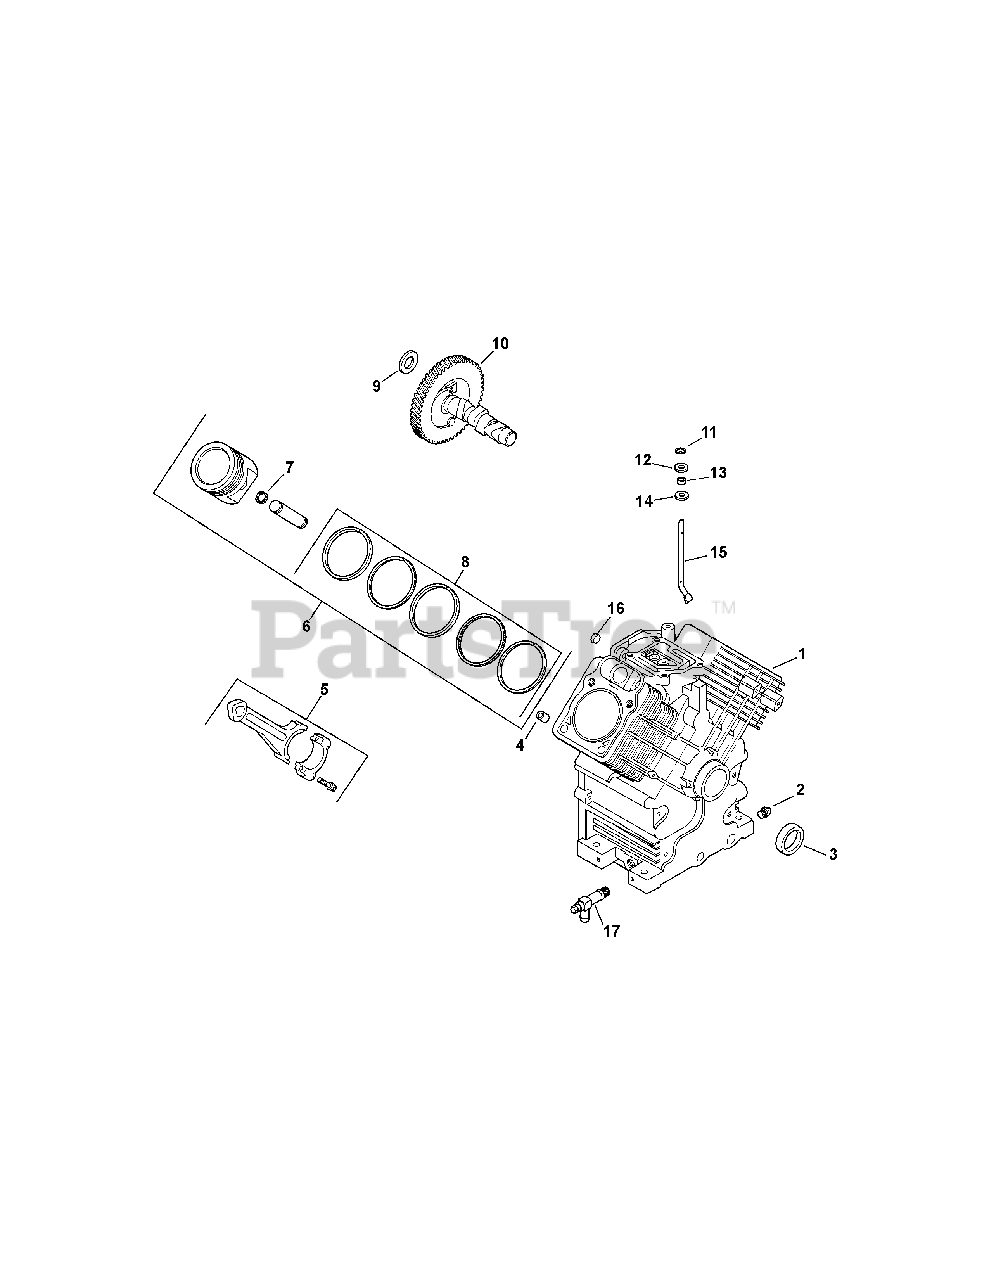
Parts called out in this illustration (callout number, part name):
1	Crankcase
2	Plug, sq. head 3/8" (2)
3	Seal, front oil
4	Pin, loYanmaring (6)
5	Connecting Rod (Std.) (2)
5	Connecting Rod (.25) (2)
6	Piston w/Ring Set (Std.) (2) (Includes 7,8)
6	Piston w/Ring Set (.08) (2)
6	Piston w/Ring Set (.25) (2)
6	Piston w/Ring Set (.50) (2)
7	Retainer, piston pin (4)
8	Ring Set (Std. & .08) (2)
8	Ring Set (.25) (2)
8	Ring Set (.50) (2)
9	Shim, camshaft (A.R.) red
9	Shim, camshaft (A.R.) black
9	Shim, camshaft (A.R.) white
9	Shim, camshaft (A.R.) blue
9	Shim, camshaft - yellow
9	Shim, camshaft (A.R.) green
9	Shim, camshaft (A.R.) gray
10	Camshaft
11	Retainer, ring
12	Washer, plain 9 mm
13	Seal, governor cross shaft
14	Washer, plain 1/4"
15	Shaft, governor cross
17	Valve, oil drain
